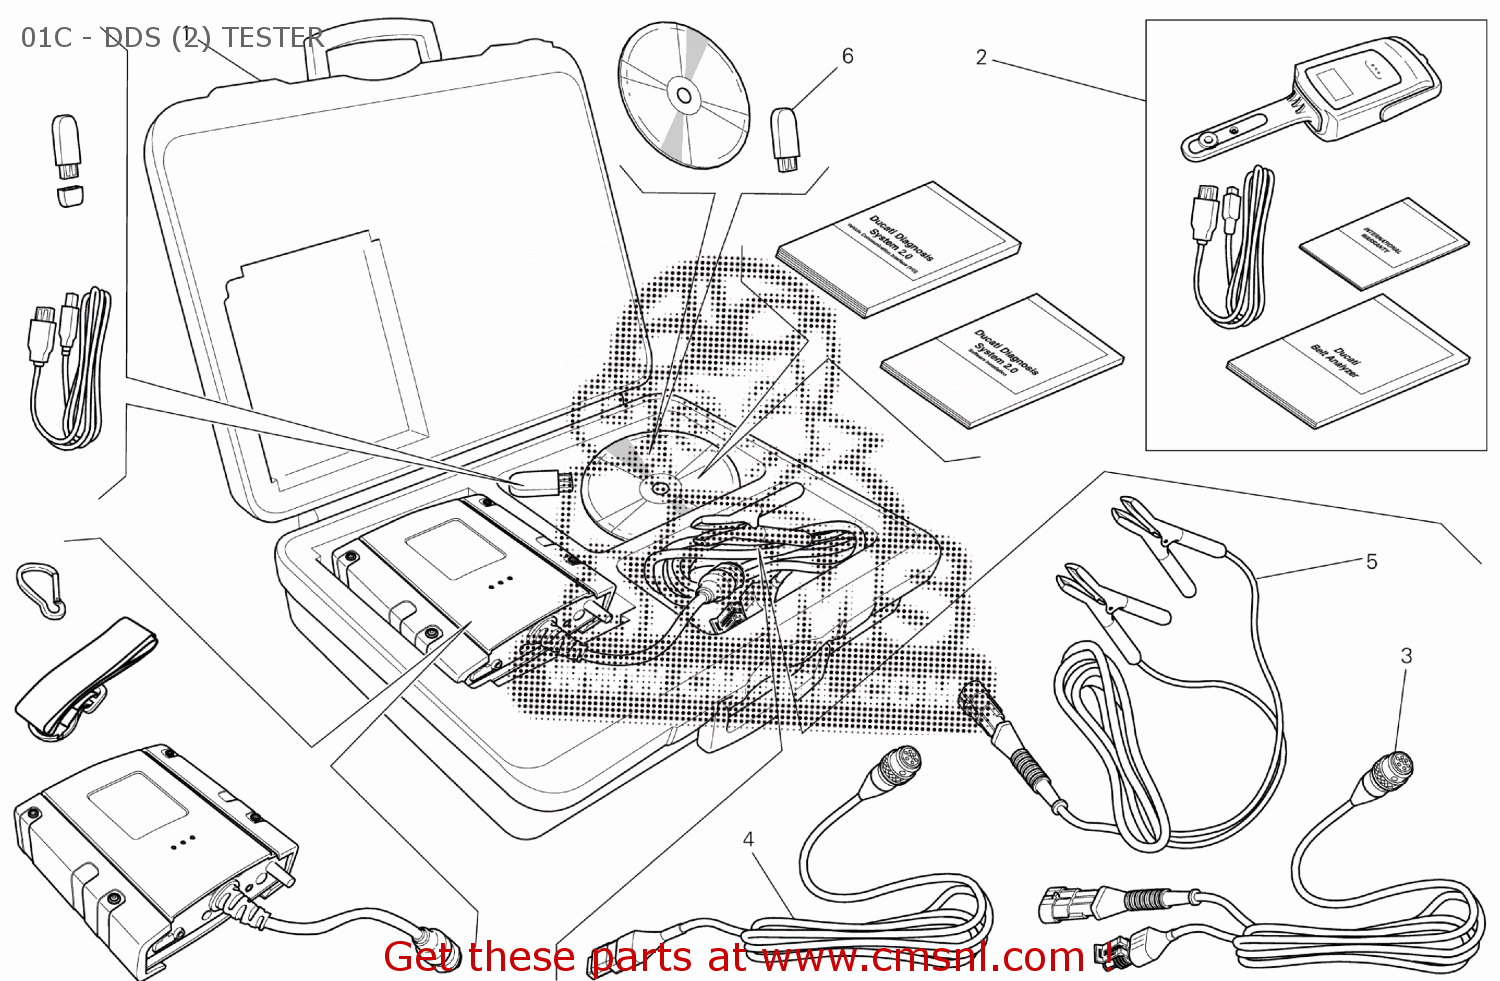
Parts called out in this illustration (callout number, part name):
1	DDS 2
2	BELT TENSIONING KIT
3	MAIN CABLE
4	MAIN CABLE
5	MAIN CABLE DDS
6	CHIAVE PC HASP DDS2.0
